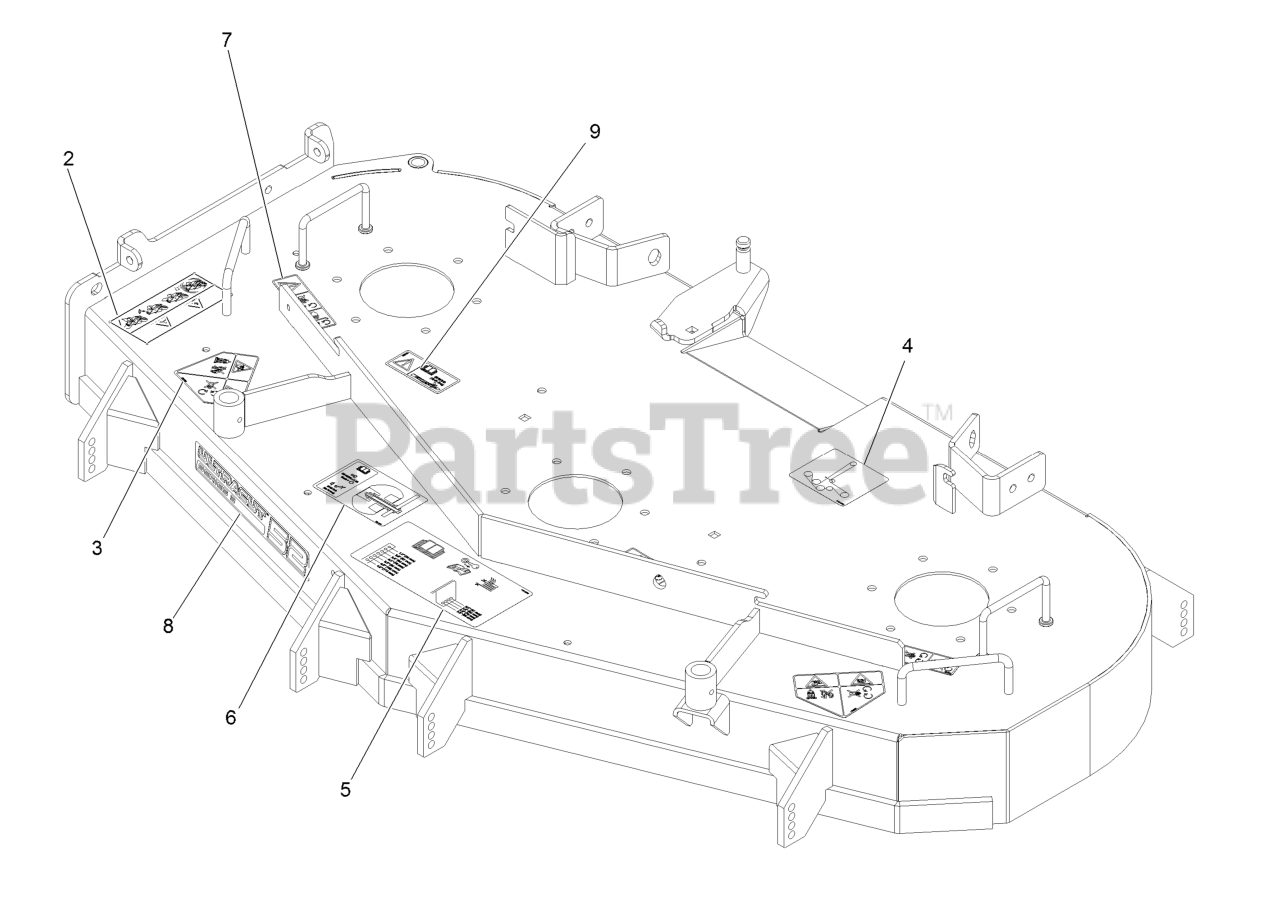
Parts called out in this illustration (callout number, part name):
2	Decal-Warning, Bagger
3	Decal-Danger
4	Decal-Belt Routing
5	Decal-Anti-Scalp
6	Decal-Roller Mounting
7	Decal-Cover, Missing
8	Decal-Ultracut 52 Series 3
9	Decal-Bolt Torque
